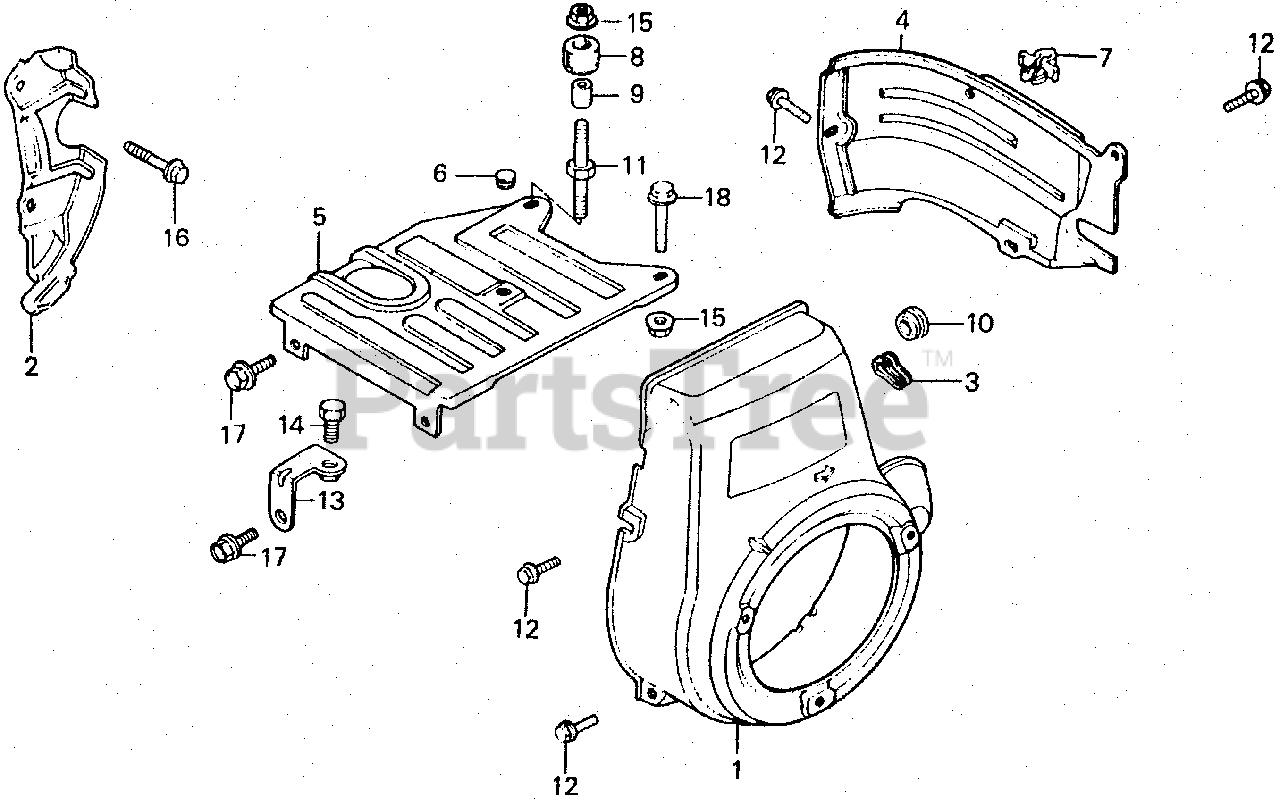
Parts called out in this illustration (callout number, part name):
1	COVER, FAN *R8* (BRIGHT RED)
2	PLATE, SIDE
3	GROMMET, FAN COVER
4	SHROUD *R8* (BRIGHT RED)
5	COVER, TOP *R8* (BRIGHT RED)
6	GROMMET, COVER
7	CLIP, IGNITION WIRE (8MM)
8	RUBBER, STOPPER (NOT AVAILABLE)
9	COLLAR, DISTANCE
10	GROMMET, DRAIN HOLE
11	BOLT, SPECIAL HEX.
12	BOLT, FLANGE (6X12) (CT200)
15	NUT, FLANGE (8MM)
16	BOLT, FLANGE (8X16)
17	BOLT, FLANGE (8X20)
18	BOLT, FLANGE (8X28)
